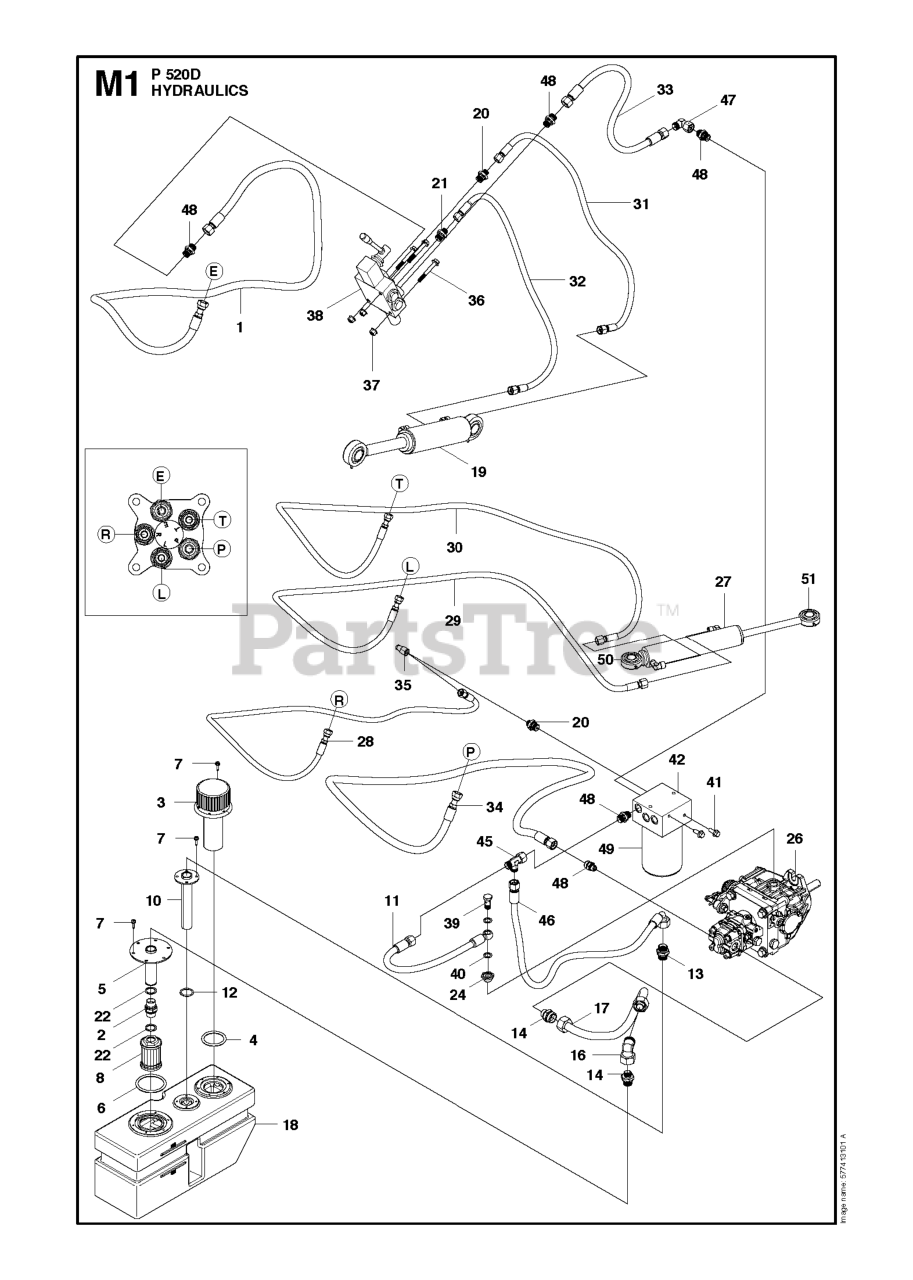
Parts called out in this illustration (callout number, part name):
2	PIPE FITTING G STRAIGHT 1/2-1/
4	O-RING 47.2X5.7 NITRIL
6	O-RING 61.2X5.7 NITRIL
8	FILTER PUMP SUCTION, AWD
12	O-RING 26.2X3.0 NITRILE
37	NUT FLANGE
40	GASKET 20X14X1.5 COPPER
